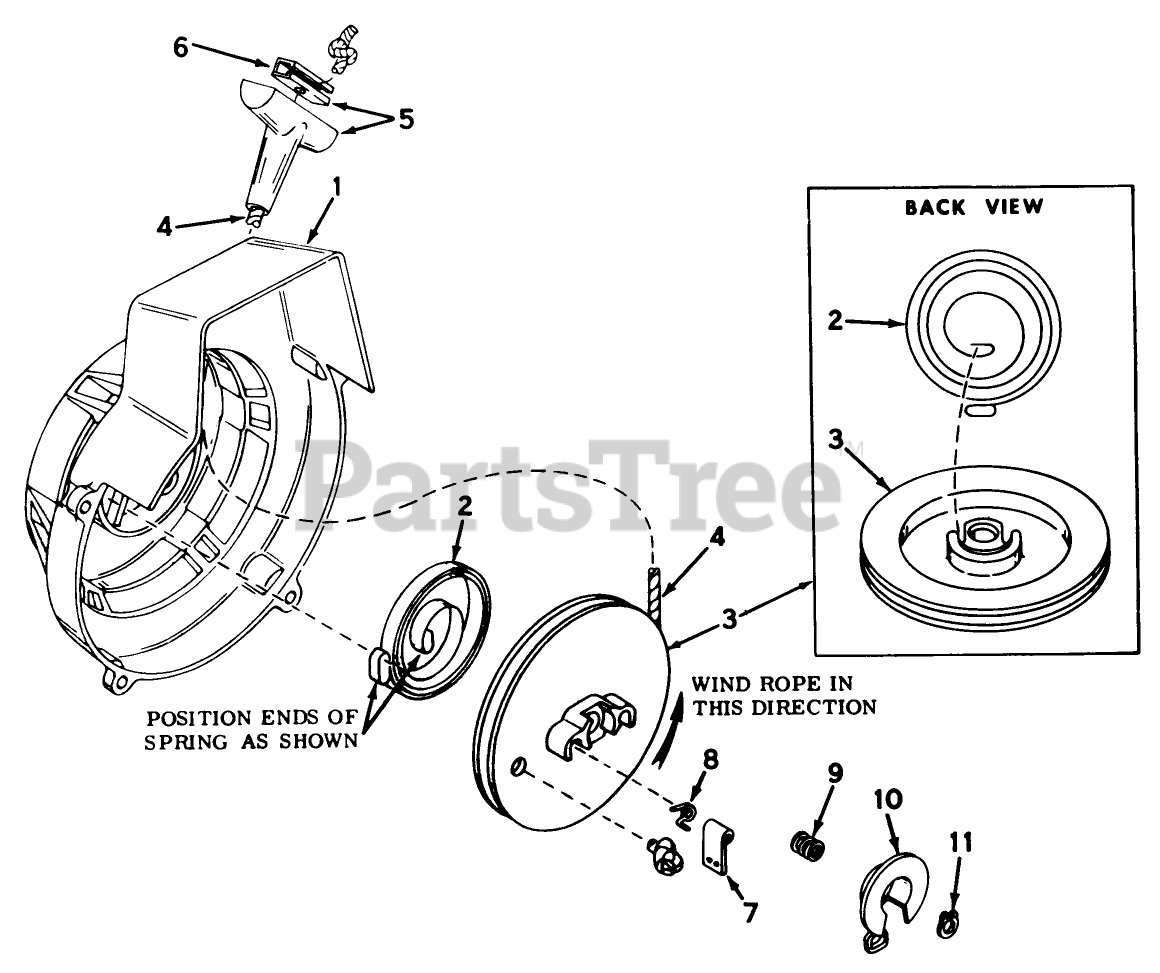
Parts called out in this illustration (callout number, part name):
1	Housing Assy., Shroud & Starter
2	Spring, Rewind
3	Pulley, Starter Rope (Incl. No. 8)
4	Rope, Starter
5	Handle Assy., Starter Rope (Incl. No. 6)
6	Insert, Handle
7	Dog, Starter
8	Retum Spring, Left Hand Wound
9	Spring, Brake
11	"E" Ring Truarc
